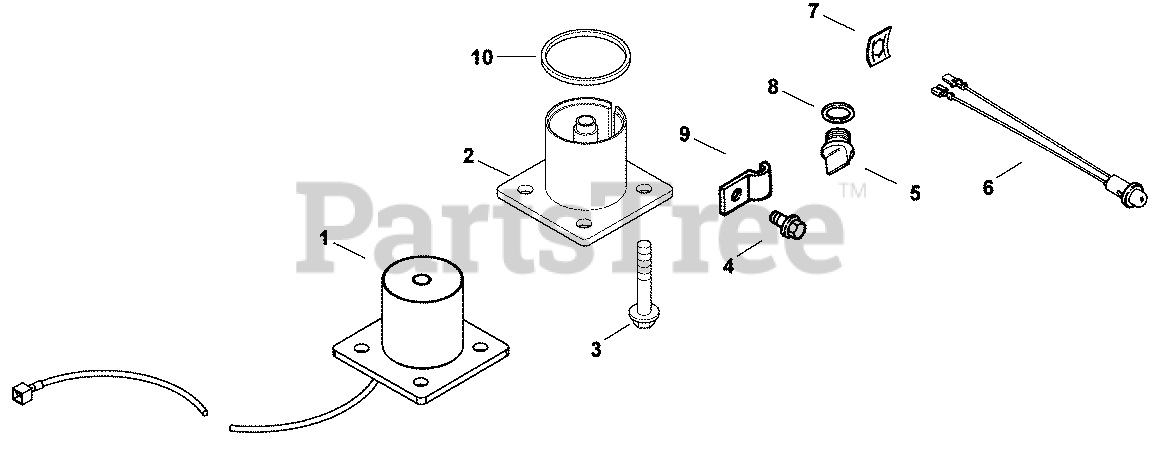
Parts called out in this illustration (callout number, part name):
1	SWITCH, VERTICAL FLOAT
3	SCREW, TORX COUNTRSUNK HD
4	SCREW, FLG THD FRM M5X.8X10
5	PLUG, OIL FILL
6	LIGHT, INDICATOR
8	WASHER, SEALING (#DSC)
9	CLIP, WIRE - DISCONTINUED
